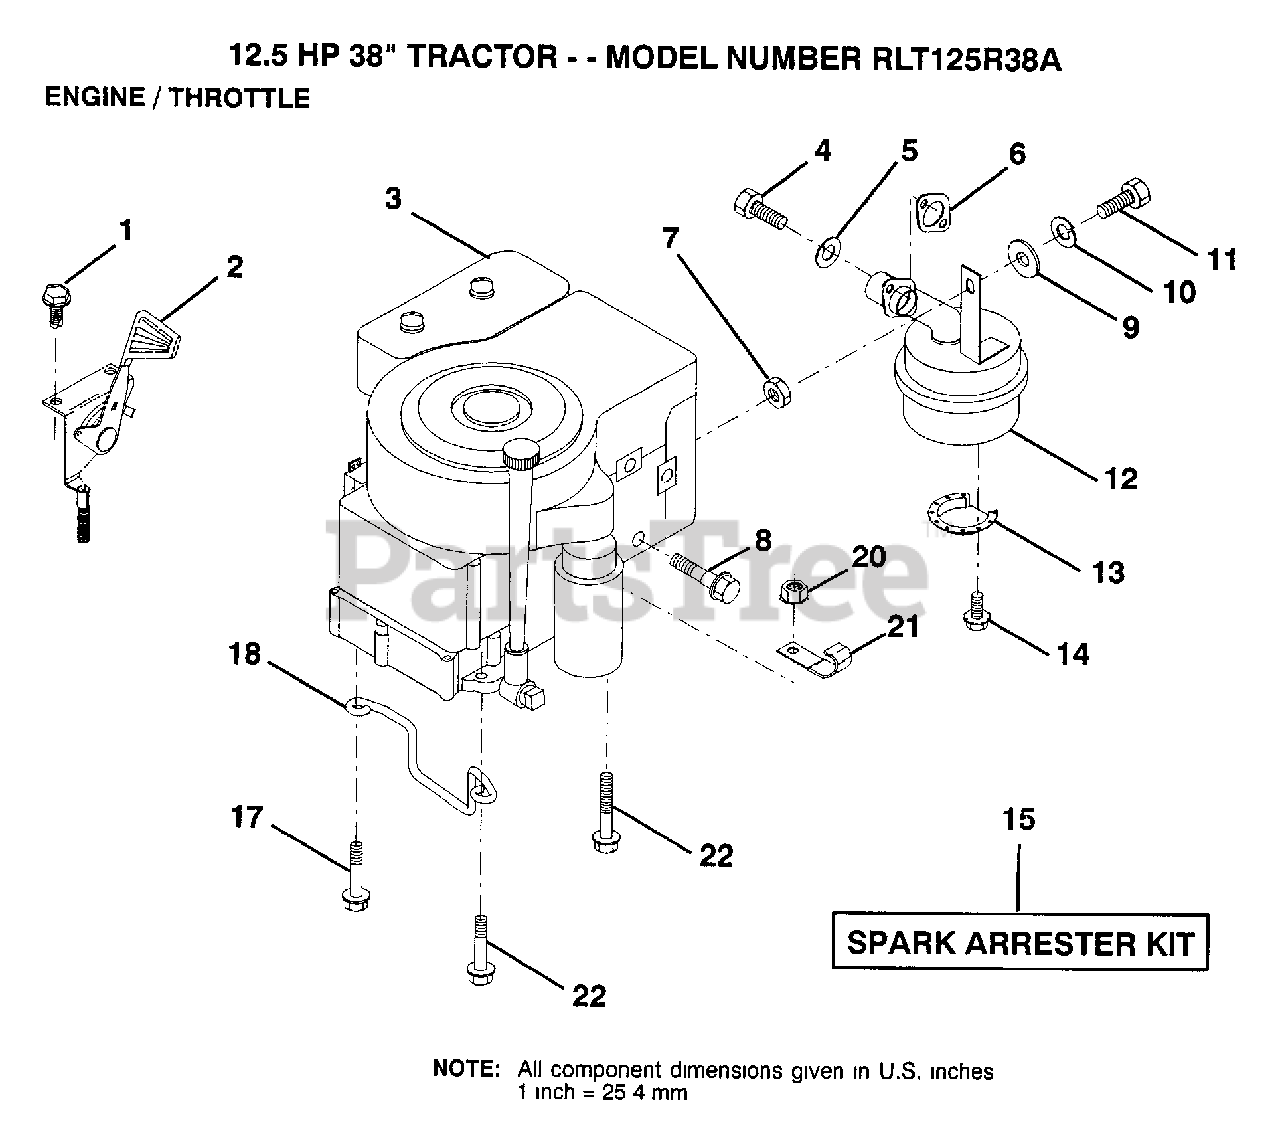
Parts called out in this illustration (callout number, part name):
1	SCREW
2	THROTTLE CONTROL
4	SCREW
5	LOCKWASHER
7	NUT.HEX.5/16-18
8	SHOULDER BOLT ST
10	LOCKWASHER
13	DEFLECTOR.222573
17	SCREW LT
18	"KEEPER,DR BELT GR"
20	NUT
21	CLIP T
22	SCREW LT
